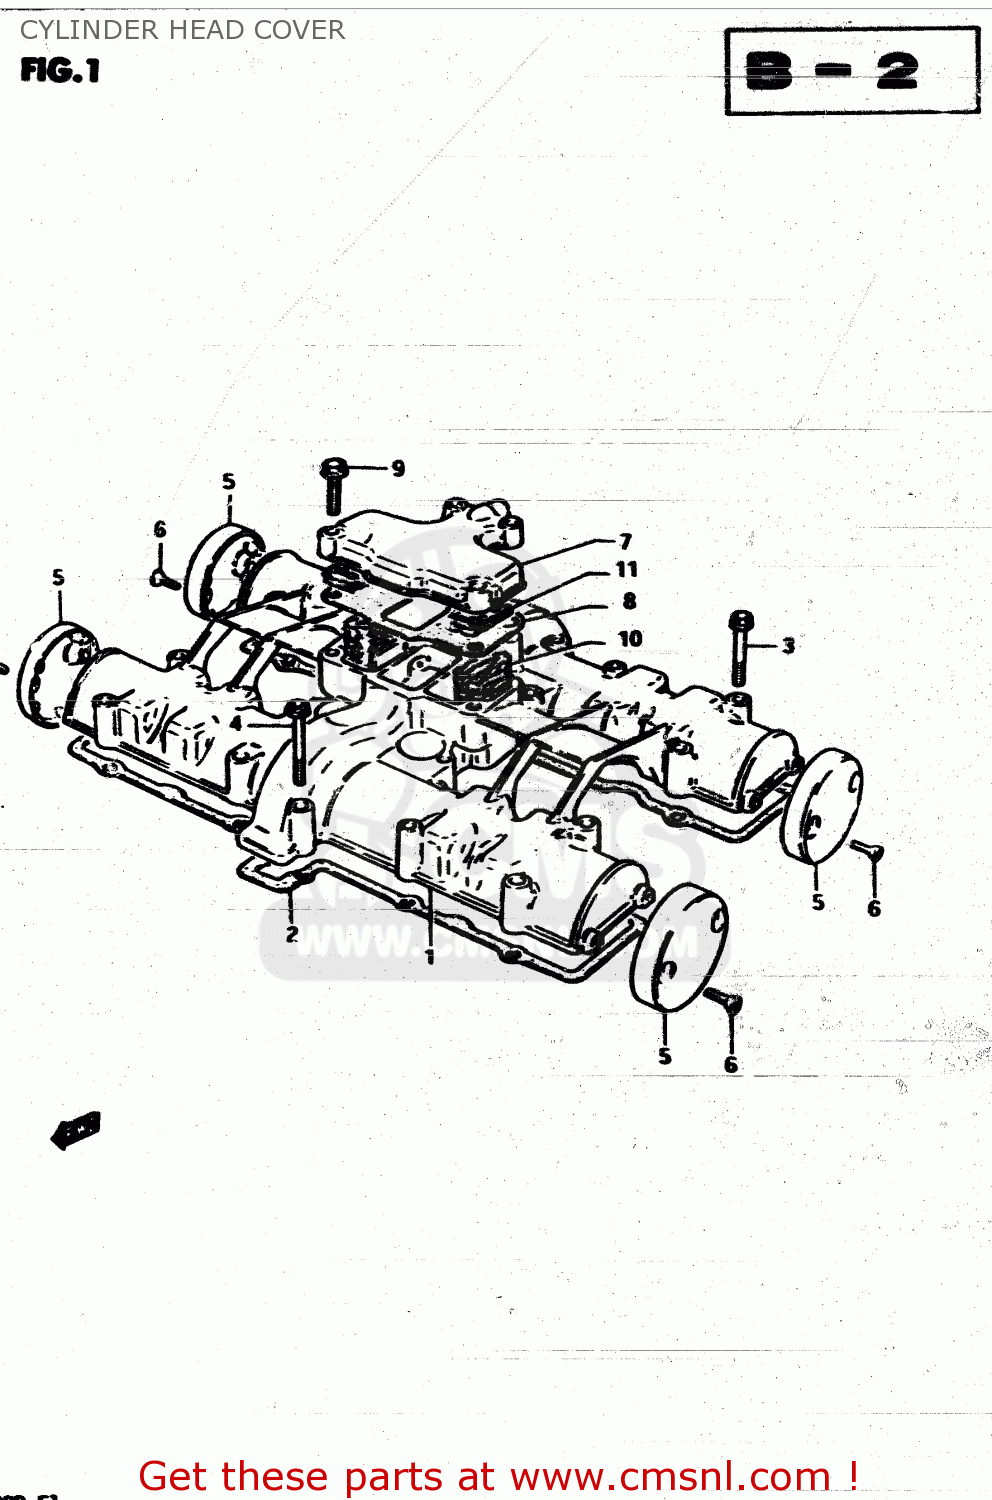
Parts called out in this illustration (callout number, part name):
1	COVER,CYLINDER
2	GASKET,CYLINDER HEAD COVER (MCA)
3	BOLT
4	BOLT,UNDER
5	CAP,CYLINDER HEAD COVER
6	SCREW(5X12)
7	COVER,BREATHER
8	GASKET (MCA)
9	BOLT
10	COVER,BREATHER
11	SEPARATOR,OIL BREATHER
